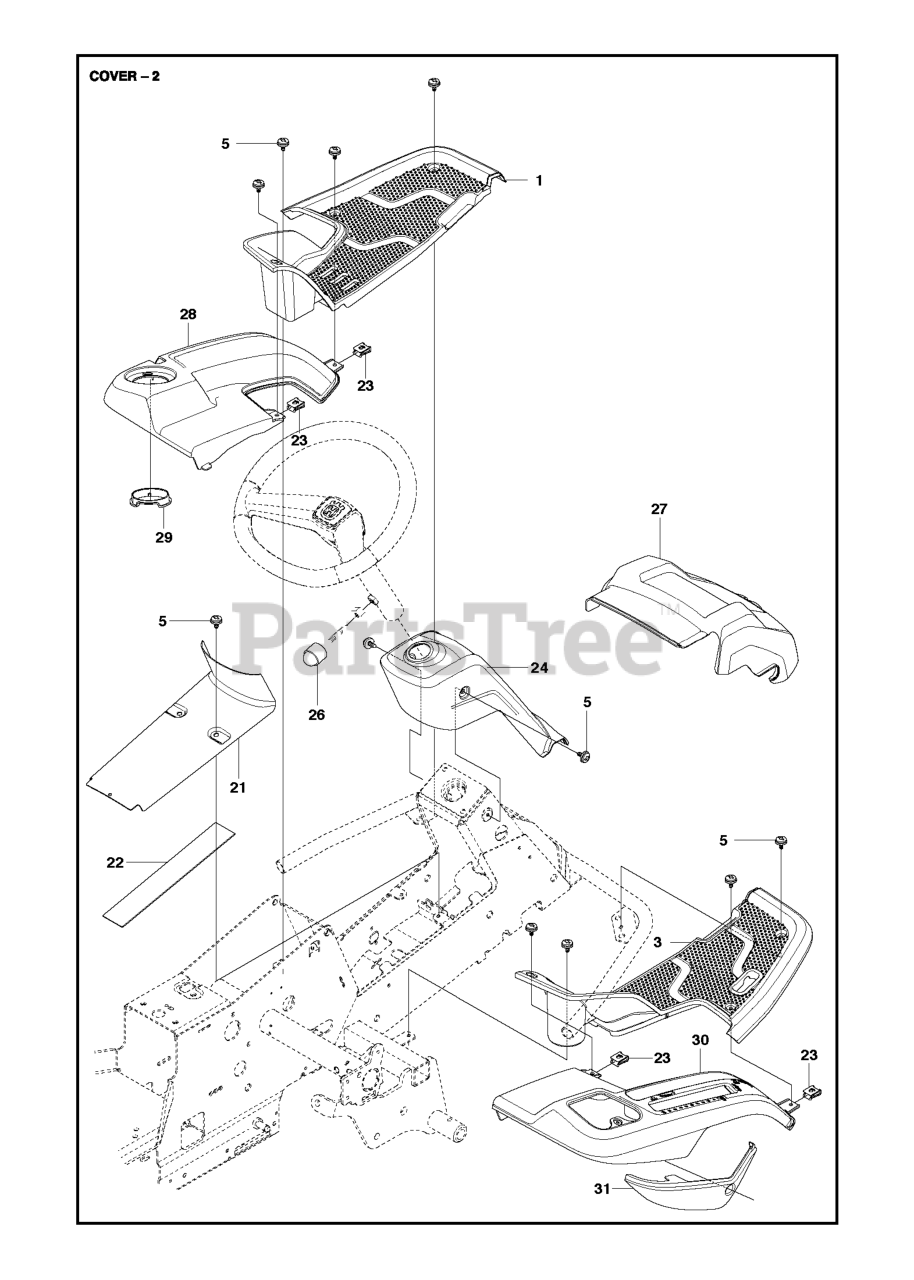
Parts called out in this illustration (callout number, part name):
1	FOOT PLATE
3	FOOT PLATE
22	MAT COVER FRAME
26	PROTECTIVE COVER
29	LOCKING NUT
31	CONTROL COVER
